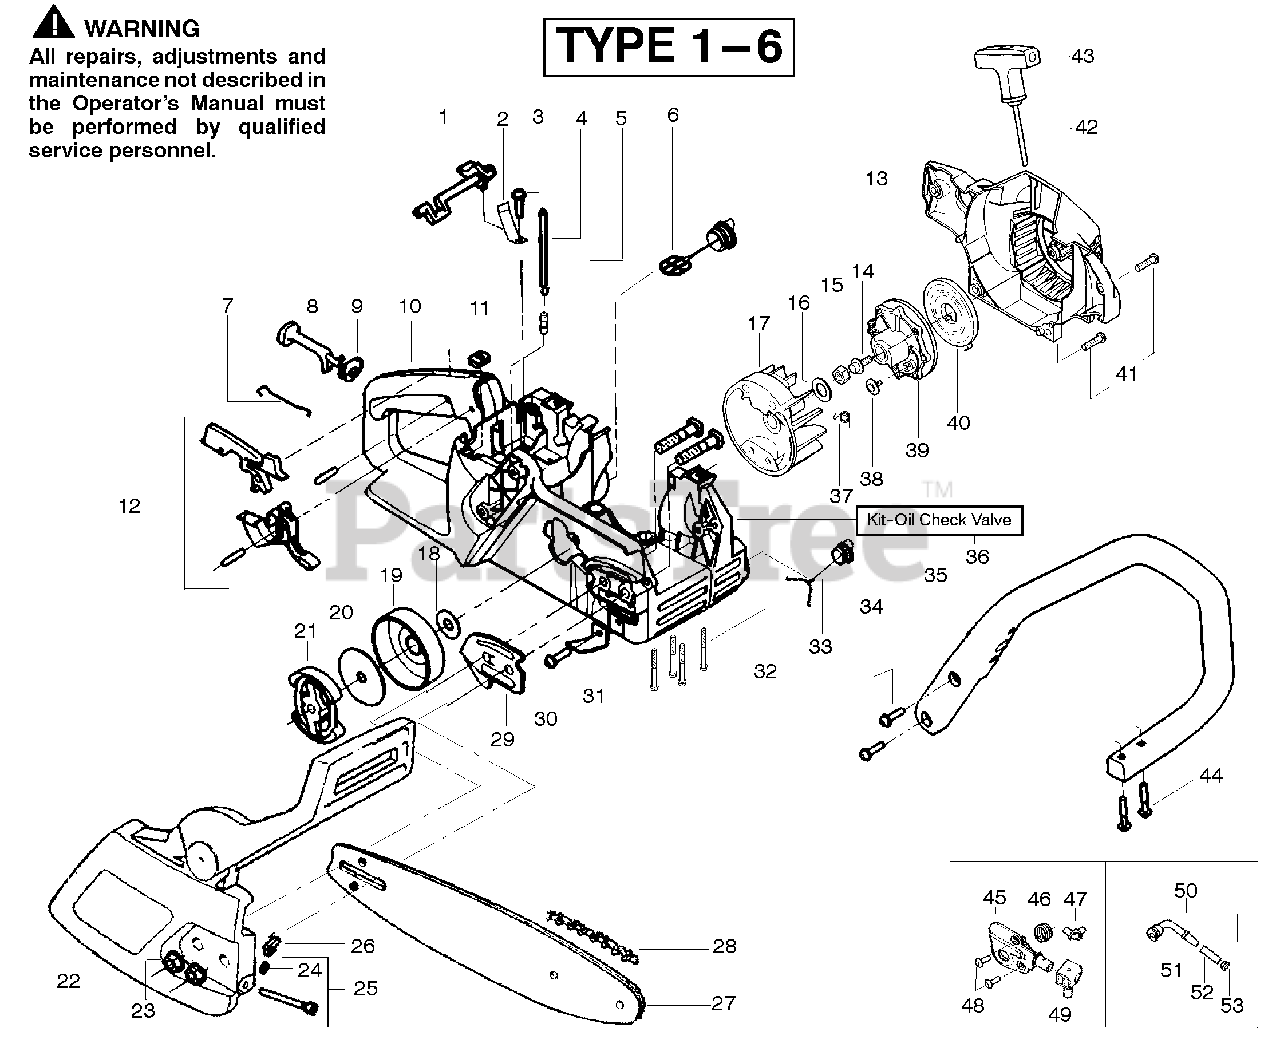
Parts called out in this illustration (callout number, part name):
1	Lever-Switch
2	Spring-Switch
4	Kit-Fuel Line (Large)
6	Assy-Fuel Cap
7	Wire-Throttle
9	Grommet-Choke Knob
12	Kit-Trigger & Lockout
16	Washer-Flywheel
17	Assy-Flywheel
18	Washer - Thrust
19	Assy-Drum W/brg.
20	Washer-Clutch
21	Assy. - Clutch
22	Assy-Chain Brake
23	Nut-Bar Mounting
24	Retainer-Bar Adjust
25	Kit-Bar Adjust
26	Pin-Bar Adjust
28	Chain-16"
29	Plate-Bar Mounting
31	Chain Catcher
33	Assy-Oil Cap
35	Handle-Front
36	Kit-Oil Check Valve
37	Spring - Starter Dog
39	Pulley-Starter
40	Spring-Starter
43	Handle-Starter
45	Kit-Oil Pump
46	Gear-Worm Spring
47	Elbow-Oil Pickup
50	Assy-Oil-Pickup
52	Filter-Oil
53	Plug-Oil Filter
